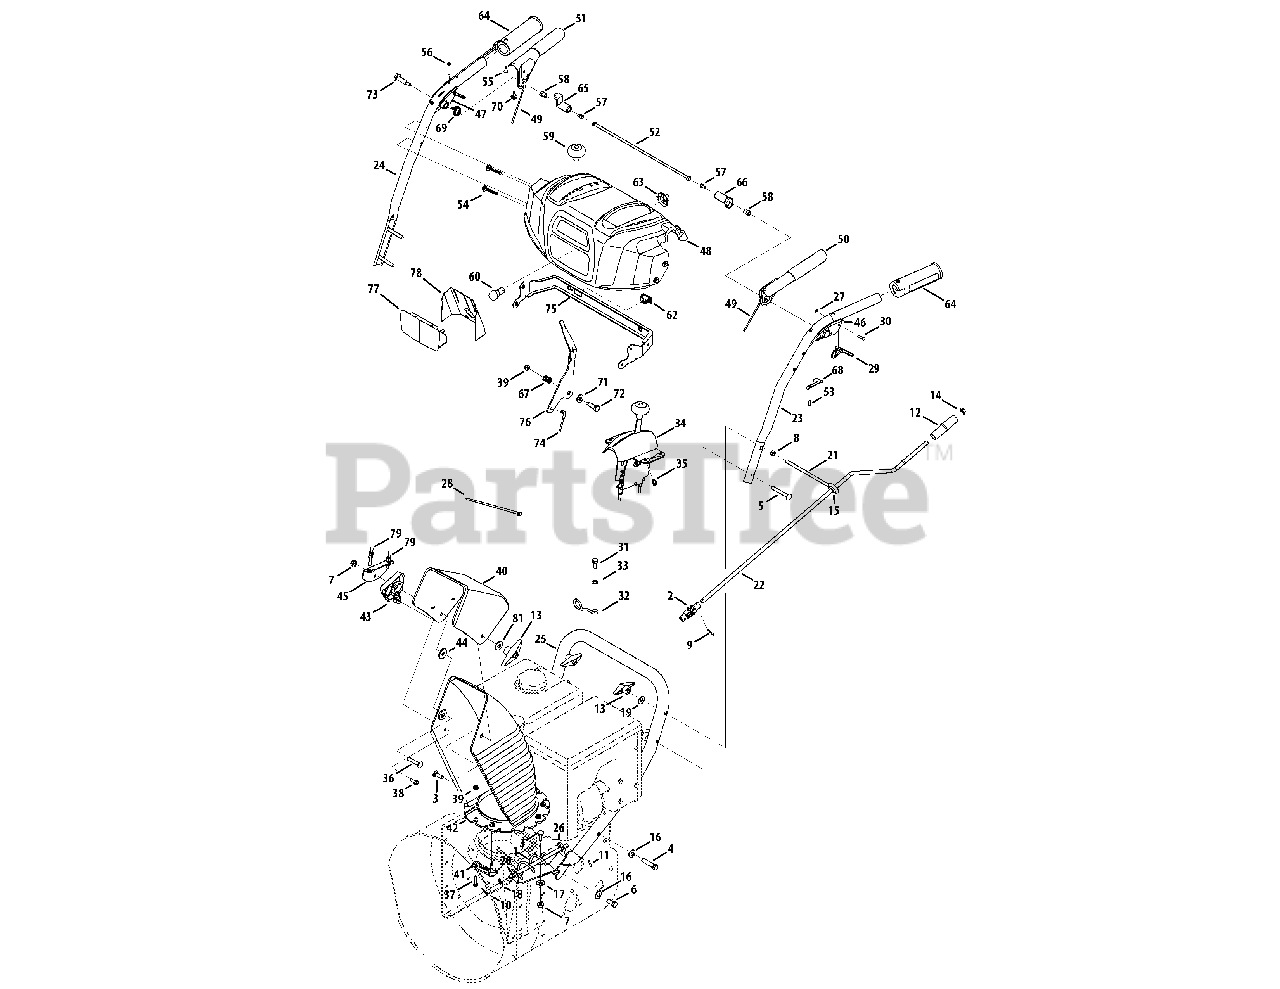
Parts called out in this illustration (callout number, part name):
1	Chute Crank Assembly
2	Joint Block Assembly
3	Screw, Carriage, 5/16-18 x 1.0
4	Screw, Hex, 3/8-16 x 2.00 Lock, Gr5
5	Screw, Carriage, 5/16-18 x 2.5
6	Screw, Hex, 3/8-16 x 1.0 Lock, Gr5
7	Flange Lock Nut, 5/16-18
8	Hex Nut, 5/16-18
9	Internal Cotter Pin
10	Internal Cotter Pin
11	Spring Pin
12	Knob, Crank
13	Knob, Wing Nut, 5/16-18
14	Cap, Push, 3/8
15	Grommet, Rubber
16	Washer, Bel, .375 x .87 x .063
17	Washer, Flat, .349 x .879 .063
18	Washer, .375 x .738 x .063
19	Washer, Belleville, .34 x .872 x .06
20	Plastic Bushing, .380 I.D.
21	Eye Bolt
23	Handle, Upper - LH
24	Handle, Upper - RH
25	Handle, Lower
26	Chute Crank Bracket
27	Ring, Retainer
28	Cable Tie
29	Trigger
30	Pin, 3/16
31	Hex Head Screw, MB 1.25
32	Cable Guide
33	Flat Washer, .330 x .630 x .0635
34	2-Way Chute Control™ Assy
35	Hi-Lo Screw, 1/4-15 x 0.5
36	Bolt, Carriage, 5/16-18 x 1.75
37	Screw, 1/4-20 x 1.00
38	Hi-Lo Screw, 1/4-15 x .75
39	Flange Lock Nut, 1/4-20
40	Upper Chute
41	Chute, Flange Keeper
42	Lower Chute
43	Chute Tilt Cable Guide
44	Flat Washer
45	Cable Bracket
46	Handle Clutch Lock - LH
47	Handle Clutch Lock - RH
48	Handle Panel
49	Cable Assembly, Auger/Drive
50	Handle Engage Assy - LH
51	Handle Engage Assy - RH
52	Rod Ass’y, Clutch Lock Pivot
53	Screw, #8-16 x 0.50
54	Screw, 1/4-20 x 1.625
55	AB Screw, #10-16
56	Screw, #10-24 x 0.375
57	Screw, 1/4-20 x.375
58	Shoulder Nut, 1/4-20
59	Shift Knob
62	Htd. Hand Grip on/off Switch
63	Light Socket
64	Heated Hand Grip
65	Lock Plate
66	Clutch Lock Cam
67	Compression Spring
68	Clutch Lock Spring
69	Torsion Spring
70	Rubber Bumper
71	Flat Washer, .385 x .87 x .06
72	Shoulder Screw
73	Shoulder Screw, 1/4-20 x 1.345
74	Speed Selector Cable
75	Panel Bracket
76	Shift Lever
77	Lens Panel
78	Reflector Label
79	Cable, Chute Tilt
80	Self-Tap Screw
81	Flat Washer, .349 x .879 x .063
